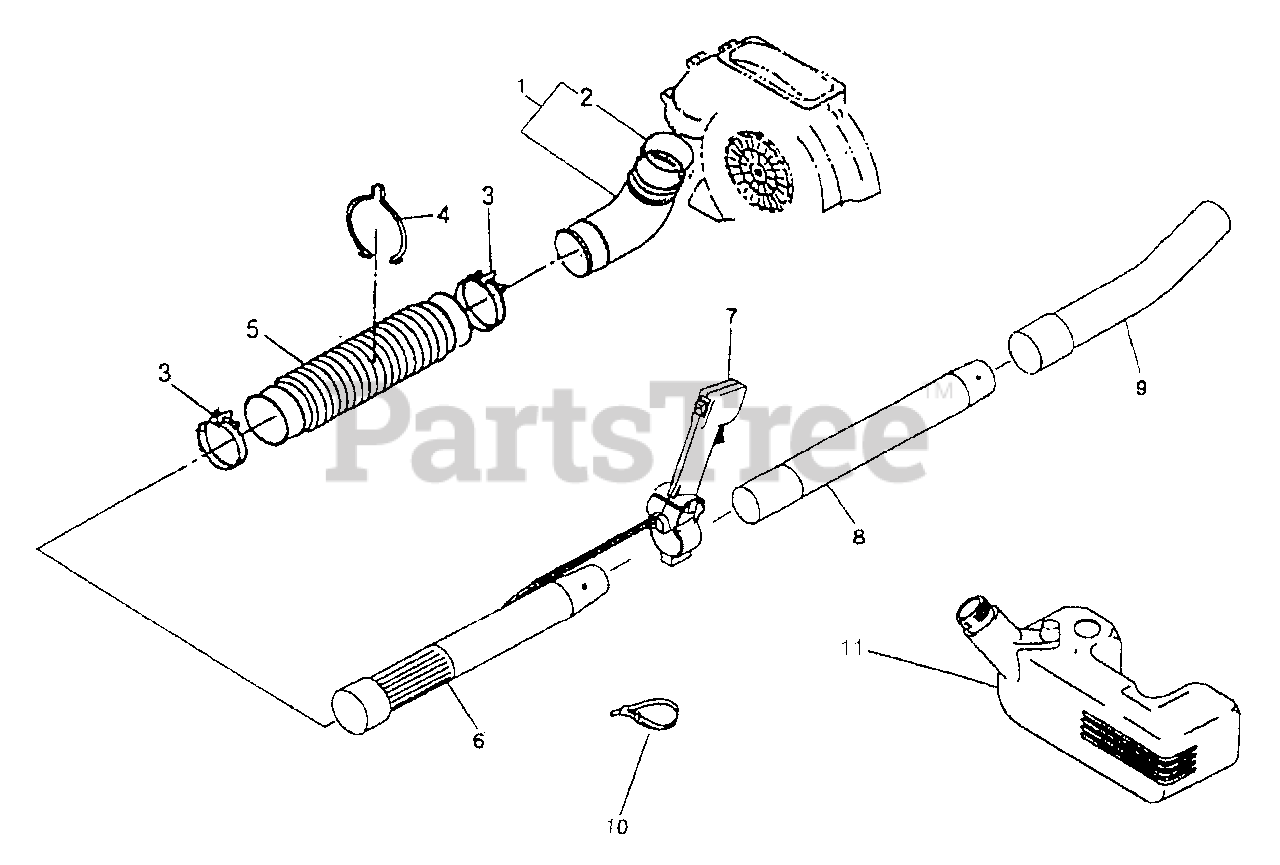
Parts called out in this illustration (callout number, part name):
1	Elbow Pipe Compl.
2	O-Ring
3	Clamp
4	Wire Clamp
5	Flexible Pipe
6	Base Pipe
7	Throttle Assy. Compl.
8	Middle Pipe
9	Bend Pipe
10	Wire Band
